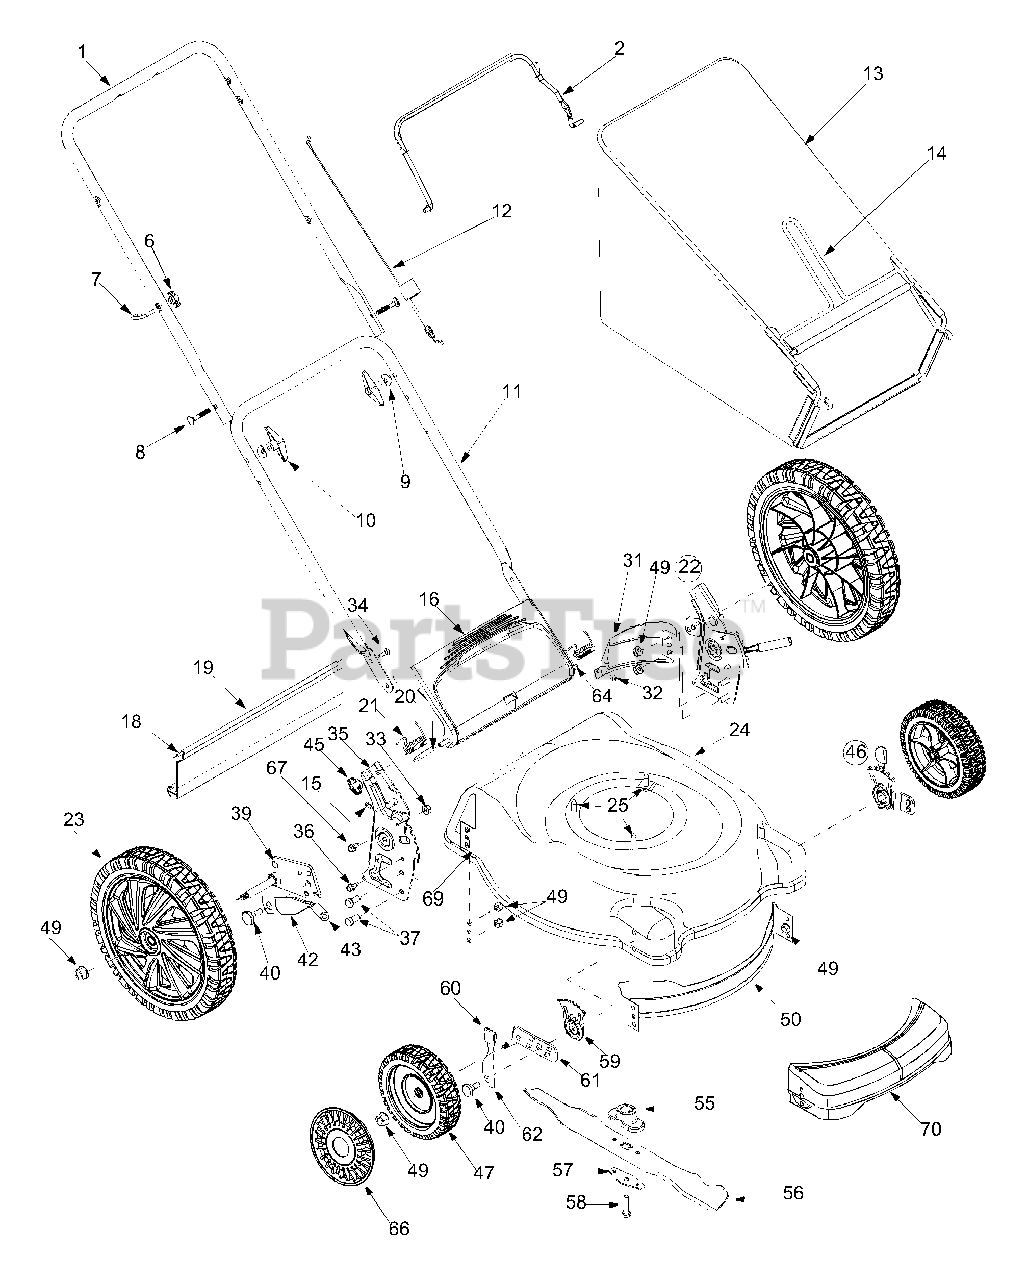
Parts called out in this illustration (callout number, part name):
6	Handle Knob
7	Rope Guide
8	Carriage Bolt 5/16-18 x 2"
9	Shoulder Washer.320 ID x.930 OD
10	Wing Nut
12	Control Cable 40"
13	Grass Bag
15	Hairpin Clip
16	Grass Bag Door
18	Wire Rod
19	Trail Shield
20	Spacer.375 O.D. x.50 I.D. x 1.02"
21	Torsion Spring - RH
22	Handle Bracket Assembly - RH
23	Rear Wheel: 12 x 2.125
25	Hex Washer Screw 3/8-16 x 1.0
32	Tap Screw 1/4-14 x.625.
33	Flange Lock Nut 3/8-16
34	Hex Carriage Screw 1/4-20
35	Handle Bracket Assembly - RH
36	TT Screw 1/4-14 x.625
37	Hex Screw 3/8-16 x 0.75
39	Pivot Bar Assembly - RH
40	Shoulder Screw
42	Rear Spring Lever
43	Spring Lever Grip
45	Wing Nut
46	Front Height Adjuster Assembly - RH
47	Front Wheel: 8 x 2.125
49	Flange Lock Nut 3/8-16
56	21" Mulching Blade
57	Blade Bell Support
58	Hex Cap Screw 3/8-24 x 1.5
59	Height Adjustment Plate
60	Knob
61	Pivot Bar Assembly - RH
62	Spring Lever
64	Chute Door Pivot Rod
66	Hubcap
67	Tap Screw 1/4-20 x.500
70	Front Cover
